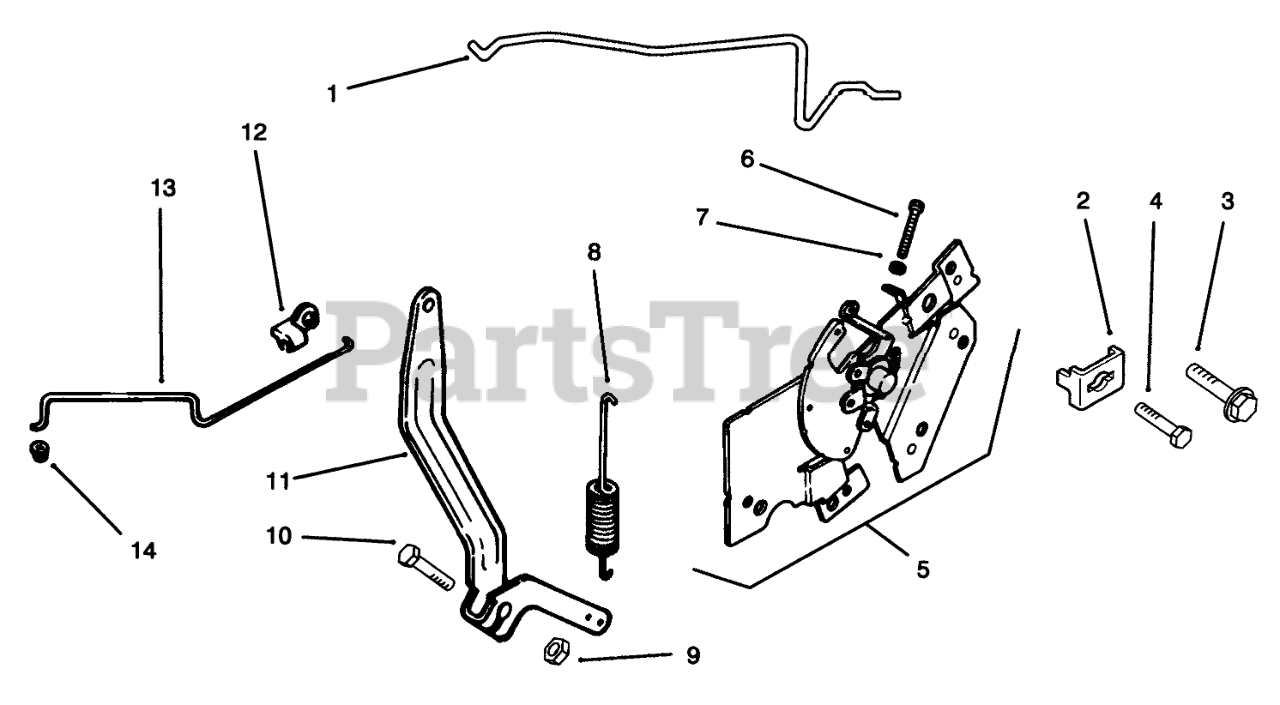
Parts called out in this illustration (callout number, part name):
1	Linkage Choke
2	Clamp
3	Screw
4	Screw-HF
5	Control-Speed ASM
6	Screw
7	Nut
8	Spring-Governor
9	Nut
10	Screw
11	Lever-Governor
12	Bushing-Linkage
13	Linkage-Throttle
14	Bushing-Linkage
